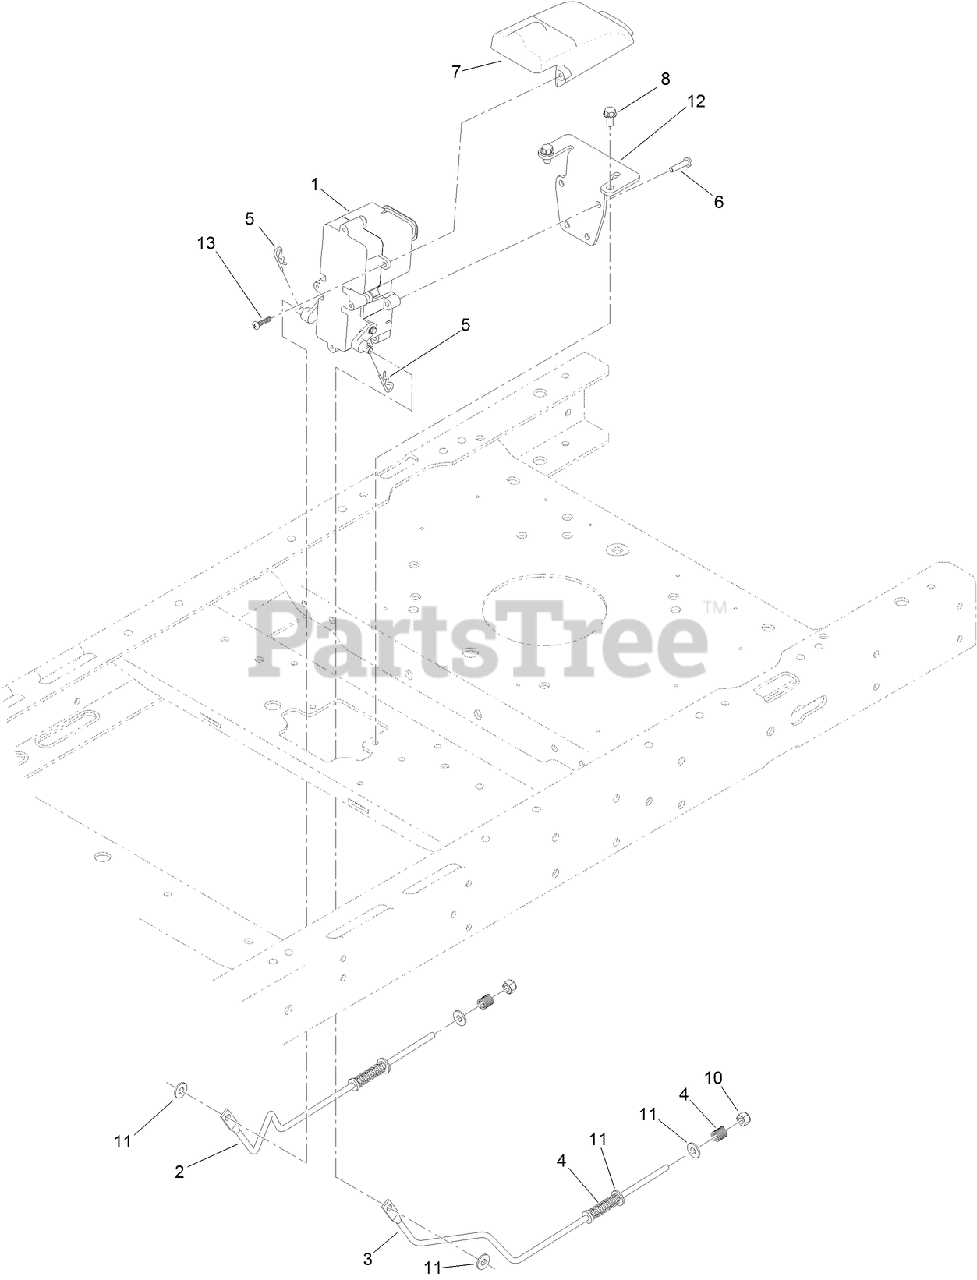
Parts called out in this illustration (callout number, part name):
2	ROD-BRAKE, RH
3	ROD-BRAKE, LH
4	SPRING-COMPRESSION
6	SCREW-PPH
7	COVER-CONNECTOR
8	SCREW-HWH
10	NUT-LOCK, NI
11	WASHER
12	BRACKET-MOUNT, BRAKE
13	SCREW-PPH
